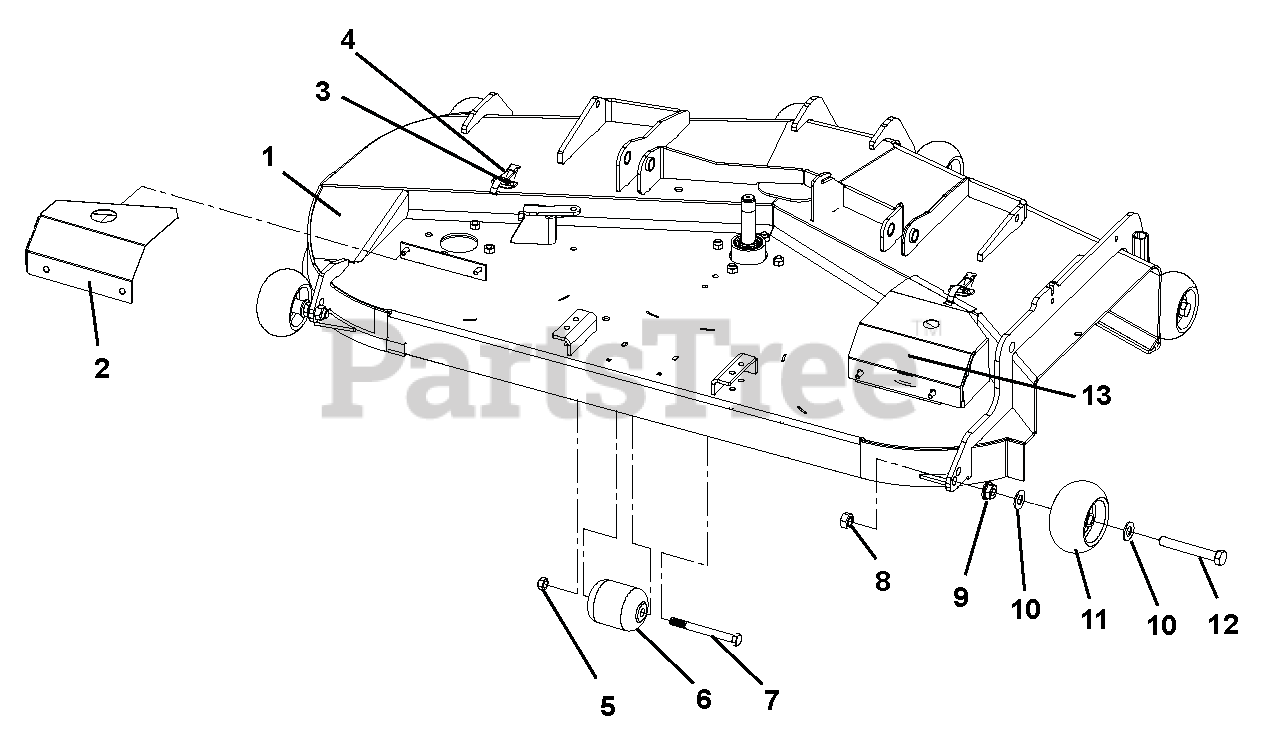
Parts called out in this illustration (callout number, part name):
1	ASSY, 54" DECK WLDT & DECALS
1	ASSY, 60" DECK WITH DECALS ACM
2	SHIELD, LH 60" DECK BELT
3	LATCH, OVERCENTER
4	RIVET, POP .188 X .375 STEEL
5	NUT-LK-CONE .50-13 GR C YWZC
6	WHEEL, GAUGE 3.00 X 3.88 SYM
7	@BLT-HEX .38-16X2.25 GR5 YWZC
8	NUT-LK-TOP .62-11 PL (ND)
9	SRATD FLNG HEX NUT 5/8-1 44412
10	@WSHR-FL-STL.656X1.31X.095 YWZ
11	WHEEL, GAUGE 5.00 X 2.52
12	@BLT-HEX .62-11X4.50 GR5 YWZC
13	SHIELD, RH 54" & 60" BELT
